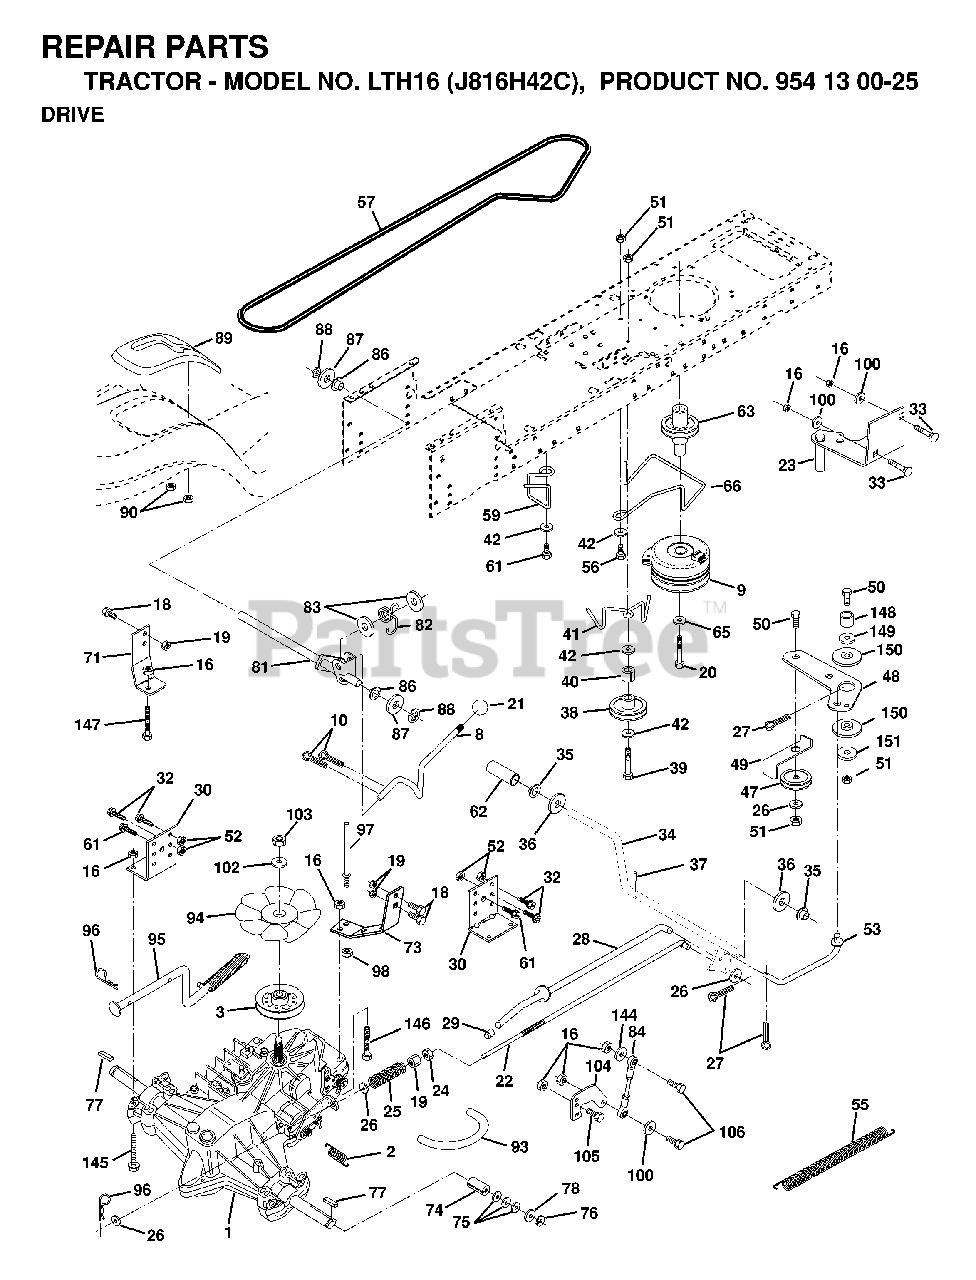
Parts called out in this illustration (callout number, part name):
2	SPRING BRAKE
3	PULLEY, TRANSAXLE
8	ROD SHIFT FENDER
9	CLUTCH, ELECTRIC
10	PIN COTTER
16	NUT.71038.31-18.HEX.NYLOCK
19	NUT
20	BOLT HEX
21	PISTOL KNOB
22	ROD BRAKE HYDRO
23	BRACKET, ASM CLUTCH MTG
24	NUT
25	SPRING ROD LT
27	COTTER PIN
28	ROD BRAKE PARK LT
29	PLUNGER CAP
30	BRACKET TRANSAXLE
32	BOLT
33	BOLT
34	SHAFT, FOOT PEDAL
35	BEARING.NYLON
36	WASHER LT
37	DRIVE PIN
38	PULLEY.IDLER.FLAT
41	KEEPER, BELT IDLER
42	WASHER
47	IDLER PULLEY
48	BELLCRANK, CLUTCH
49	RETAIN BELT
50	BOLT
51	LOCKNUT
52	LOCKNUT
53	LINK, CLUTCH LT
55	SPRING, RETURN LT
59	KEEPER CENTER SPAN
61	SCREW
62	PEDAL COVER T
63	PULLEY, CLUTCH ELECT EVX
65	LOCKWASHER
66	KEEPER BELT ENGINE
68	STRAP LH TORQUE
73	STRAP TORQUE RH HYDRO
74	SPACER SPLIT
76	E-RING LT
77	SQUARE KEY
81	SHAFT ASSY
82	SPRING,TORSION
83	WASHER
88	KLIP RING
92	HEX BOLT
93	FUEL LINE
94	FAN 7" HYDRO
95	CONTROL ARM, BYPASS HYDRO
96	RETAINER M
97	KEEPER BELT RH
100	WASHER M
103	NUT.HEX.1/2-20
104	CONTROL ARM
106	BOLT.5/16-18X1-1/4 FULL.THREAD
144	WASHER
146	BOLT
148	GUIDE
149	SPACER RETAINER
150	BUSHING NYLON COLLERED
151	WASHER 12/32X2X10GA
